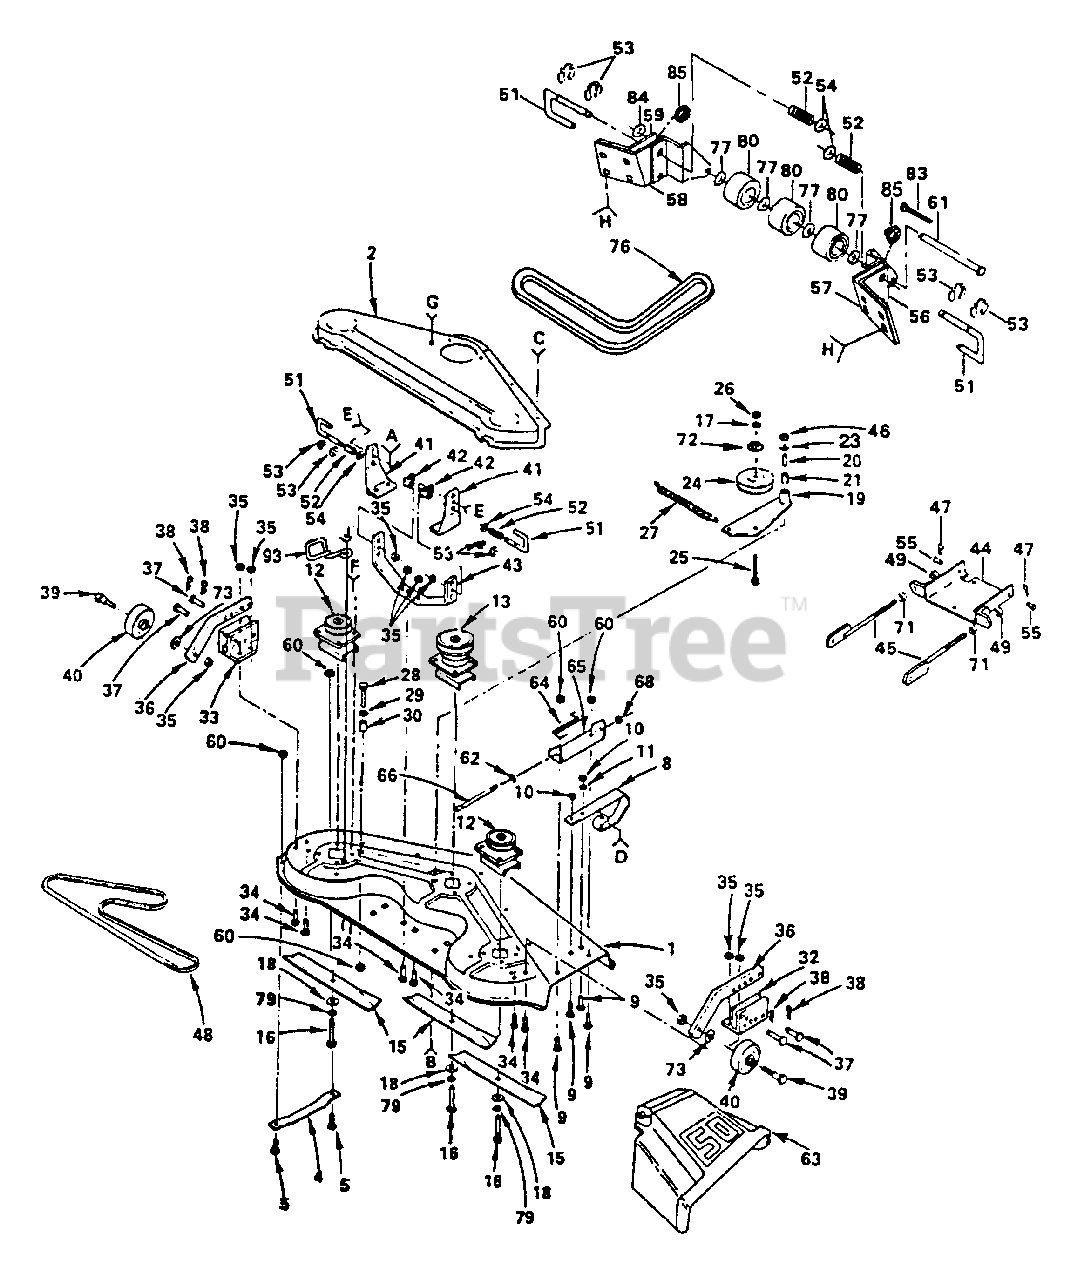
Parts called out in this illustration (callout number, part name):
1	Housing, Mower
2	Cover, Drive, Deck
4	Runner, L.H.
5	Bolt, Carriage 5/16-18 x 5/8
8	Runner
9	Bolt, Carr. 5/16-18 x 3/4
10	Locknut 5/16-18
11	Washer 11/32 x 11/16 x 16 Gauge
12	Mandrel, Secondary
13	Mandrel, Primary
16	Bolt, Hex 3/8-24 x 1-1/2 Grade 5
17	Washer, Lock 3/8
18	Washer 13/32 x 1-1/4 x 12 Gauge
19	Arm Assembly, Idler
20	Liner, Bearing
21	Bearing
23	Washer 11/32 x 1-1/8 x 16 Gauge
24	Pulley, Idler
25	Bolt, Hex 3/8-16 x 1-1/2
26	Nut, Hex 3/8-16
28	Bolt, Hex 5/16-18 x 1-1/4 Grade 5
29	Washer 11/32 x 3/4 x 16 Gauge
30	Spacer, Split
32	Bracket, Ga. Wheel, R.H.
33	Bracket, Ga. Wheel, L.H.
34	Bolt, Carriage 3/8-16 x 3/4
35	Nut, Crownlock 3/8-16
36	Bar, Ga. Wheel
37	Pin, Clevis
38	Retainer, Spring
39	Bolt, Shoulder
40	Wheel, Gauge
41	Bracket, Suspension
43	Brace, Suspension
44	Plate Assembly, Mower Suspension
45	Bracket, Suspension
46	Nut, Hex 5/16-18
47	Clip, Hairpin
49	Nut, Crownlock 1/2-13
51	Pin, Release
53	Ring, Klip
54	Washer 17/32 x 1 x 12 Gauge
55	Pin, Clevis
56	Bracket, Outer, R.H.
57	Bracket, Inner, R.H.
58	Bracket, Inner, L.H.
59	Bracket, Outer, L.H.
60	Locknut 5/16-18
61	Pin, Pivot
62	Washer 11/32 x 5/8 x 16 Gauge
63	Shield, Deflector
64	Spring, Deflector
65	Bracket, Deflector
66	Rod, Hinge
71	Nut, Hex 3/8 x 16
72	Washer 13/32 x 1 x 14 Gauge
73	Washer 17/32 x 15/16 x 12 Gauge
77	Washer 15/32 x 1 x 10 Gauge
79	Washer, Lock 3/8
80	Roller, Nose
83	Pin, Cotter
84	Washer 15/32 x 1 x 16 Gauge
93	Keeper, Belt L.H.
